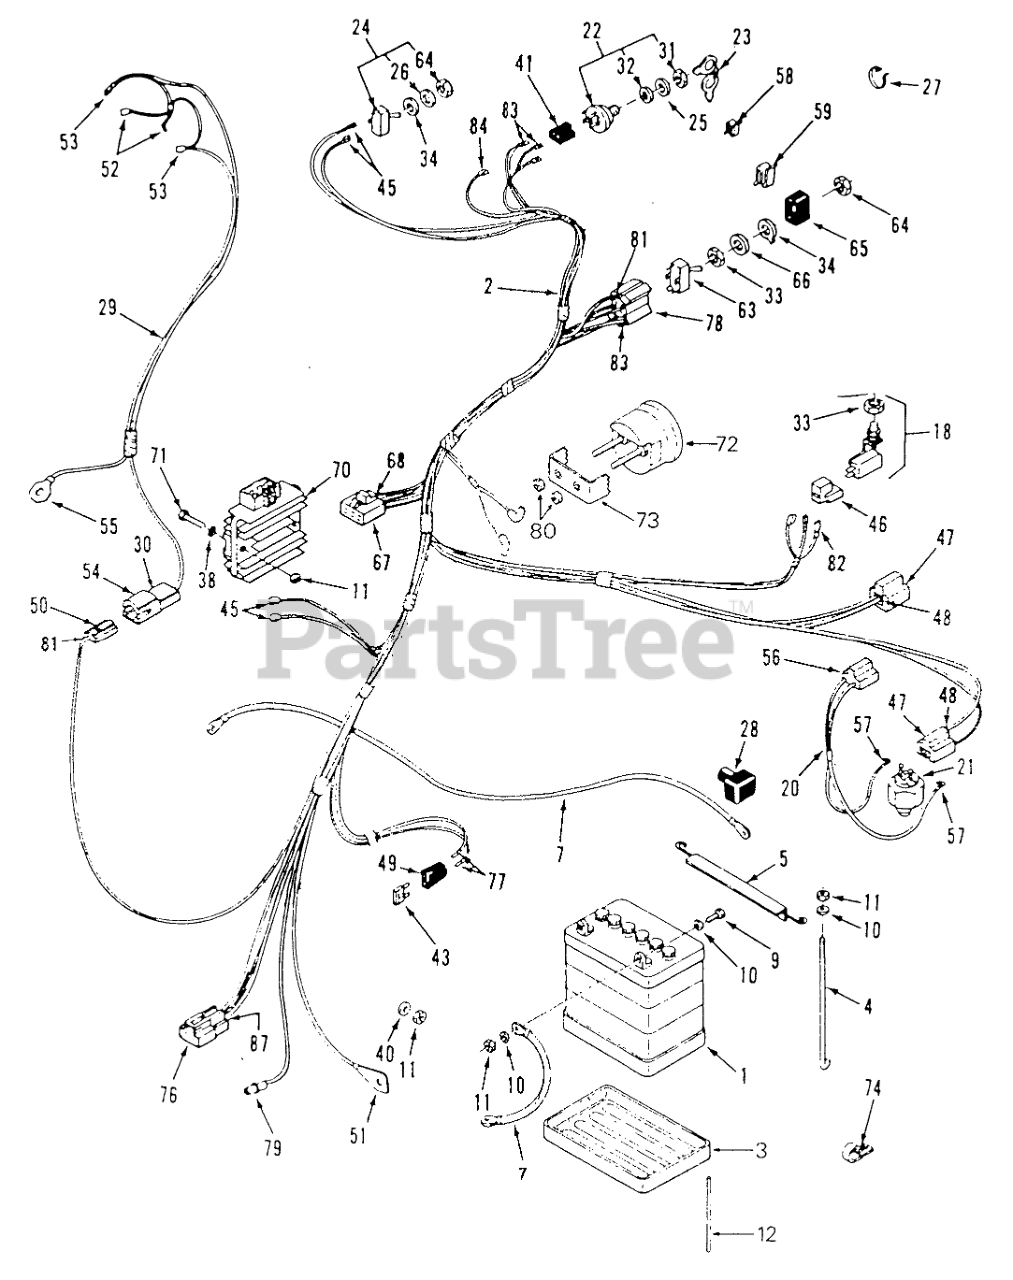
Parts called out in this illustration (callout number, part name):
1	Battery
2	MAIN-HARN & WIRE DIA
3	TRAY-BATTERY
5	HOLDDOWN-BATTERY
7	WIRE - 14" BLACK
9	Bolt
11	Nut
12	TUBE-BATTERY DRAIN
18	Seat Switch
20	ASSY WIRING HARNESS
21	SWITCH (N.C.-TRANS)
22	Ignition Switch (Includes Items 31 & 32)
23	Ignition Key
24	Light Switch (includes items 33 & 34)
25	Washer
26	Washer
27	PLASTIC TIE
28	Boot
29	HARNESS-HEADLIGHT
32	LOCKWASHER
33	NUT-HEX, SPECIAL
34	TAB-WASHER
38	LOCKWASHER
40	Washer
41	CONNECTOR-5 WAY-SERV
43	FUSE-BLADE, 15 AMP
45	Connector .250 x .032
46	CONNECTOR BODY
47	CONNECTOR BODY
48	TERMINAL-LONG MALE
49	FUSE-BLOCK ASS'Y
50	CONNECTOR BODY
51	Ring Terminal
52	Male Terminals (Part of 1)
53	Female Dbl. Crimp Terminal (part of item 29) 211
54	Connector Part of 5
55	Ring Terminal (part of item 2)
56	CONNECTOR BODY B
57	TERMINAL-TAB RCPT
58	CLIP
59	SPEED CLIP
63	Electric Clutch Switch (includes items 33,34 & 64)
65	COVER-PTO SWITCH
66	WASHER
67	CONNECTOR BODY
70	REGULATOR VOLTAGE
71	HHCS 1/4-20X1" WHIZ
72	Hourmeter Gauge (only used on 212-H)
73	Gauge Mtg Bracket (only used on 212-H)
74	CLAMP
75	MOUNTING-CLIP CONN
76	3-CONTACT LOCK-TYPE
77	Fuse Holder Term. (1 used on 212) 208, 211
78	CONNECTOR 5 WAY
79	Connector-Socket
80	Nut (only used on 212-H)
81	Wire Terminal (Part of 1)
82	Wire Terminal (Part of 1)
83	Male Terminals (Part of 1)
84	Belt Guide-Bottom 308 Only
87	Long Male Terminal .248 x .032
